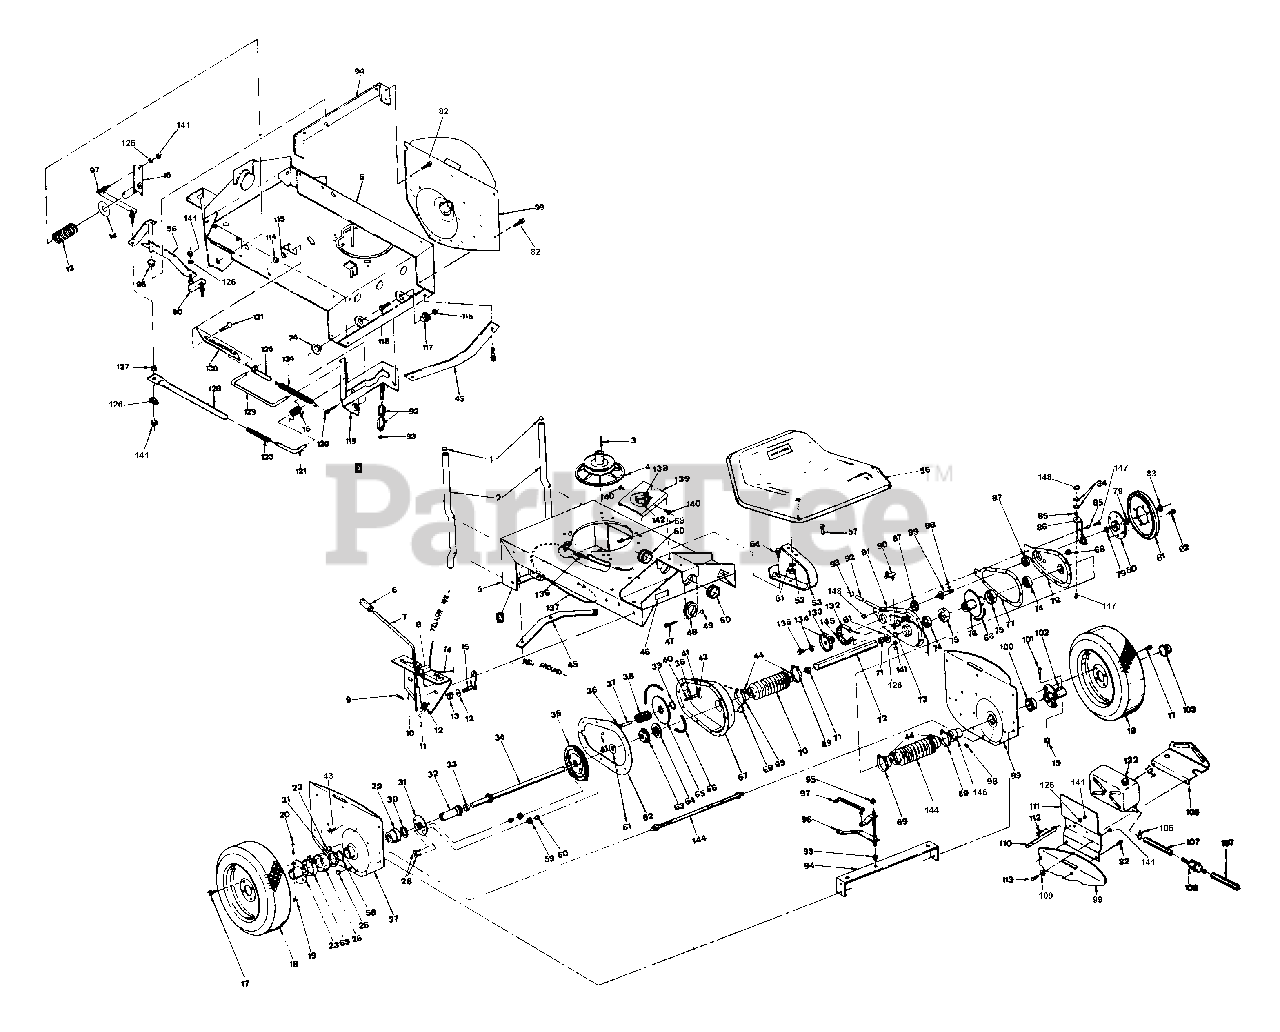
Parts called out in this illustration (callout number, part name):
1	Cap
2	Bumper
3	Key
4	Drive Disc Assembly
5	Main Case
6	Grip
7	Shift Handle
8	Neutral Switch
9	Clovis Pin
10	Shift Detent
11	3/32 x 3/4 Cotter Pin
12	Thrust Washer
13	Spring
14	Mower Clutch Wire
15	Shift Handle Arm
16	Spring
17	Lug Bolt
18	Wheel and Tire Assembly
18	Wheel and Tire Ass'y.
19	5/16-24 Lock Nut GR5
20	Wheel Bolt, R.H. Axle Bolt
21	Oil Seal
22	5/16 Flange Lock Nut
23	Right Hand Wheel Hub
24	Thrust Washer
25	5/16-24 Lock Nut
26	Seal Cap, R.H.
27	Fender, R.H.
28	5/16-24 x 1-5/8 H H Lock Cap Screw
29	Bearing
30	Thrust Washer
31	Differential Plate
32	Short Axle Assembly
33	SPACER, Differential (1.25" ID x .425 Wide)
34	Long Axle Assembly
35	63T, 10P Gear
36	5/16 Belleville Washer
37	Spacer
38	Gear, 11T, 10P
39	Retaining Ring
40	Idler Bolt
41	O-RING, 5/16"
42	5/16 Internal Tooth Lock Washer
43	1/4-20 x 5/8 Self Tapping Screw
44	Seal Ring
45	Hitch Plate
46	Name Plate
47	5/16-24 x 2-1/2 Hex Head Cap Screw
48	Tube Clamp
49	5/16-24 Flange Lock Nut
50	Grommet
51	7/16 lock Washer
52	7/16-14 Hex Nut
53	Seat Spring
54	3/8-16 x 1 Hex Head ST. Screw
55	Washer
56	Seat
57	7/16-14 x 1 Carriage Bolt
58	Clamp Ring
59	12 Tooth, 12 Pitch Gear
60	Pinion Spacer
61	Flange Washer
62	Gasket
63	Sprocket
64	Washer
65	Sprocket
66	Chain
67	Case
68	Plastic Plug
69	Boot Clamp
70	Boot
71	Bearing
72	ASSEMBLY, Drive Hex Tube
73	Nylon Washer
74	Needle Bearing
75	Nylon Thrust Washer
76	Right Hand Wheel Hub
77	Gasket
78	Cover, Left Hand
79	Belleville Washer
80	Hub
81	Driven Disc (R/B 7018782)
82	5/16-18 x 5/6 HWST
83	5/8-18 Hex Lock Nut
84	Washer
85	Split Spacer
86	Brake Lever Assembly
87	Bearing
88	Woodruff Key
89	Sprocket and Shaft
90	Shift Link, Short
91	Cover, Right Hand
92	Roller
93	Retaining Ring
94	Cross Brace
95	Nylon Bearing
96	Shift Arm
97	Shift Link, Long
98	Grease Fitting
99	Fender, Left Hand
100	CAP, Seal L.H. 3/4"
101	Axle Bolt, Left Hand
102	Hub, Left Hand
103	Hub Cap
104	5-Quart Tank
105	Front Bracket
106	Hose Clamp
107	Fuel Hose
108	Filter
109	Washer
110	Tank Brace
111	Bracket, Back
112	5/16-24 x 1 HHCS
113	5/16-24 x 5/8 Hex Head Cap Screw
114	3/8-16 Hex Nut
115	3/8 lock Washer
116	5/16-18 Hex Nut
117	Yoke Bearing, R.H.
118	5/16-18 x 1 Self Tapping Screw
119	LIFT, Yoke
120	3/16 x 3/4 Cotter Pin
121	Rod
122	Gas Cap
123	Spring
124	Spring
125	Clutch Clevis
126	5/16" SLW
127	Roller
129	Clutch Rod
130	Rod Guide
131	3/8-16 x 3/4 Carriage Bolt
132	Auxiliary Brake Band
133	Brake Drum
134	Belleville Washer
135	3/8-24 x 1/2 HHCS
136	Brake Spring
137	Brake Cable Housing
138	Manual Start Switch
138	SWITCH, Electric Start
139	PANEL, Switch (NLA, use 38240 and drill .641" switch hole)
140	1/4-20 x 3/8 HWST
141	NUT, 5/16-24 Hex
142	Interlock
143	Boot, LH (replaced by 75115)
144	Tie Rod
145	Belleville Washer
146	Bearing, LH Fender (w/fitting)
147	1/4"-28x3/4" HHCS
148	1/4"-28 HN
